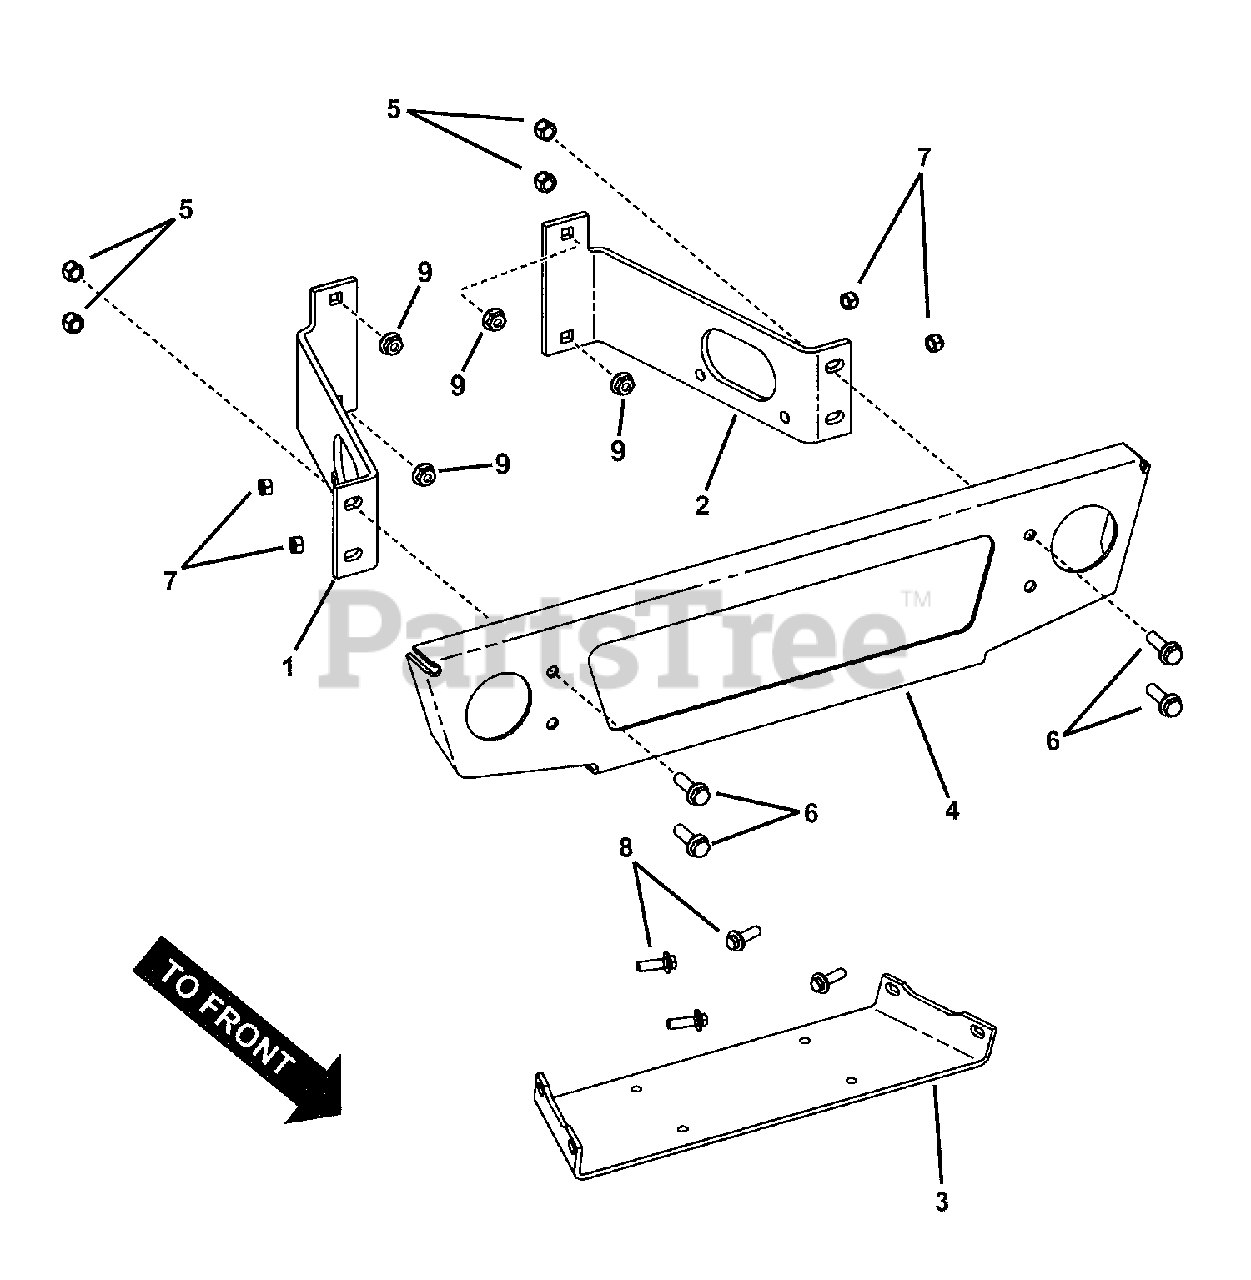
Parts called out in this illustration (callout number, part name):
1	BUMPER SUPPORT, LH
2	SUPPORT, Bumper
3	PLATE, Winch
4	BUMPER
5	NUT, 3/8-16 Hex Nyloc
6	BOLT, 3/8-16 x 1-1/4" Hex Flange Lock
7	NUT, 5/16-18 Hex Nyloc
8	BOLT, 5/16-18 x 1" Hex Flange Lock
9	NUT, 3/8-16 Hex Flange Lock
